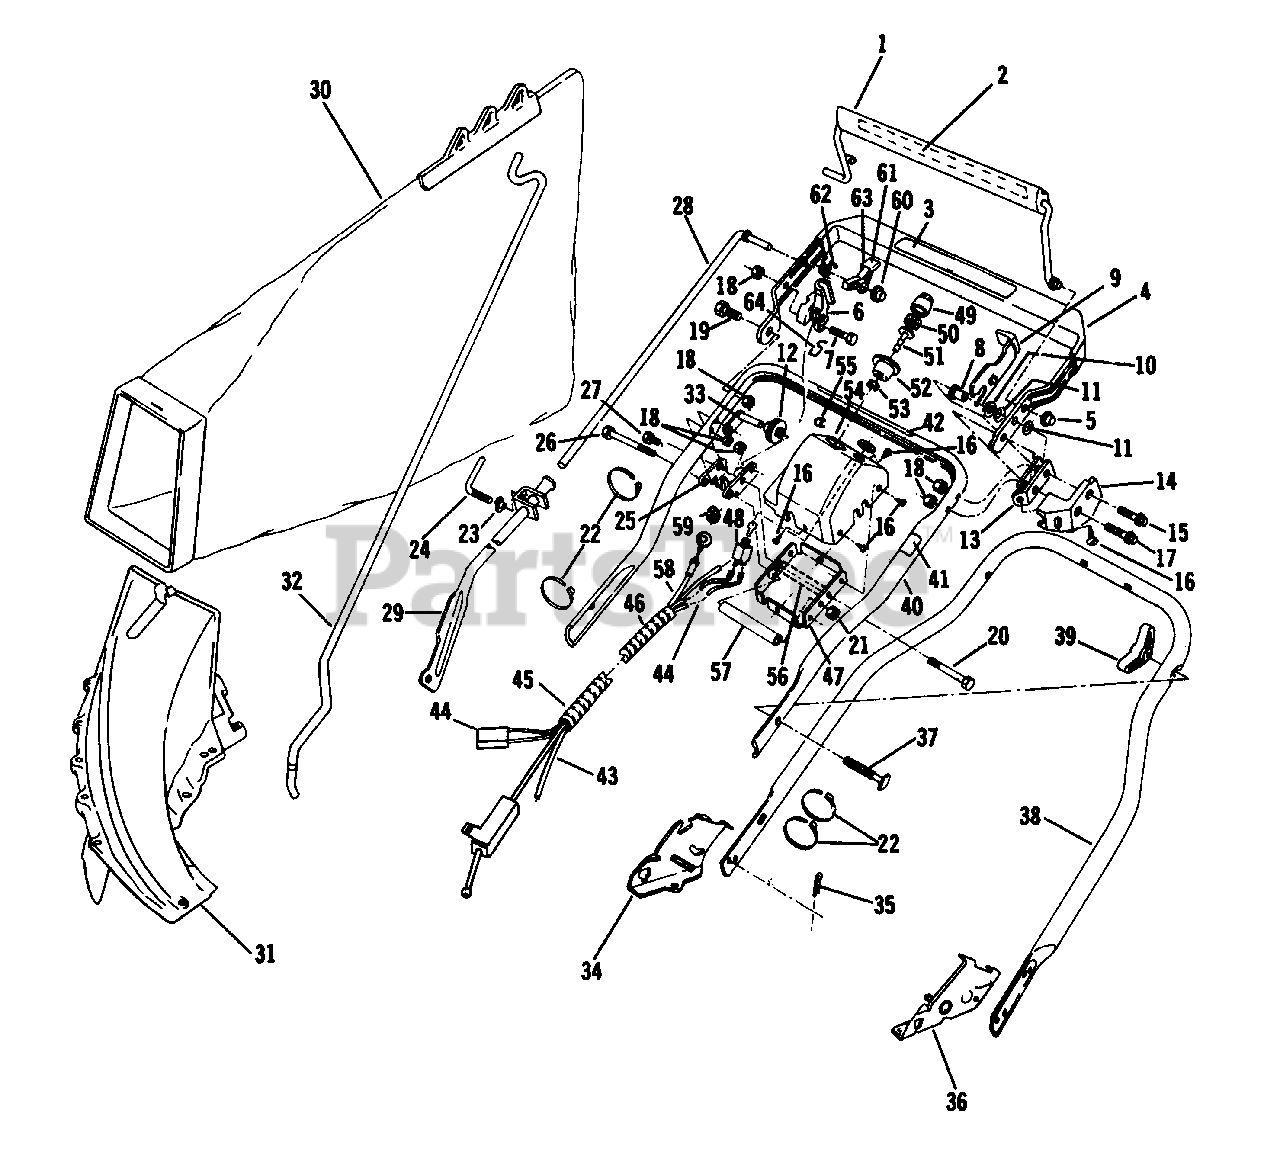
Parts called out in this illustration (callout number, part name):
1	Control Lever Assembly-Bail
2	Decal-Blade Control
3	Decal-Drive Control
4	Top Handle and Grip Assembly
5	Pushnut
6	Cam-Cluth Cont. Bail
7	Bolt-Hex
8	Spacer-Flanged
9	Lever-Lockout
10	Washer-Plain
11	Washer-Spring
12	Pulley
13	Down-Stop
14	Guard-Lockout
15	Bolt-Shoulder
16	Screw-"Taptite"
17	Bolt-Shoulder-L.H.
18	Locknut
19	Bolt-Shoulder-R.H.
20	Screw-Hex Hd. Cap
21	Nut-Hex Jam
22	Tie Strap
23	Nut-Cont. Lvr. Clamp
24	Lever-Rod Clamp
25	Bracket-Clutch Cable
26	Screw
27	Screw-Clutch Cable Brkt.
28	Rod-Control
29	Control Lever Assembly
30	Bag Assembly
31	Chute Assembly
32	Rod-Grass Bag
33	Pivot-Bracket Pulley
34	Bracket-Handle-R.H.
35	Hair Pin
36	Bracket-Handle-L.H.
37	Screw
38	Handle Section-Bottom
39	Knob
40	Handle Section-Center
41	Decal-Drive Lockout
42	Decal-Starting Inst.
43	Tubing-Primer
44	Wire Harness Assembly
45	Spiral Tubing
46	Spiral Tubing
47	Plate-Cover Assembly
48	Switch Assembly
49	Primer Bulb
50	Filter
51	Primer Base
52	Cup
53	Locknut
54	Cover
55	Decal
56	Spacer
57	Spacer
58	Control Cable Assembly
59	Ring-Retainer
60	Pushnut
61	Decal-Stop-Latch Lever
62	Spring-Torsion
63	Stop-Latch Lever
64	Retainer-Cable to Cam
